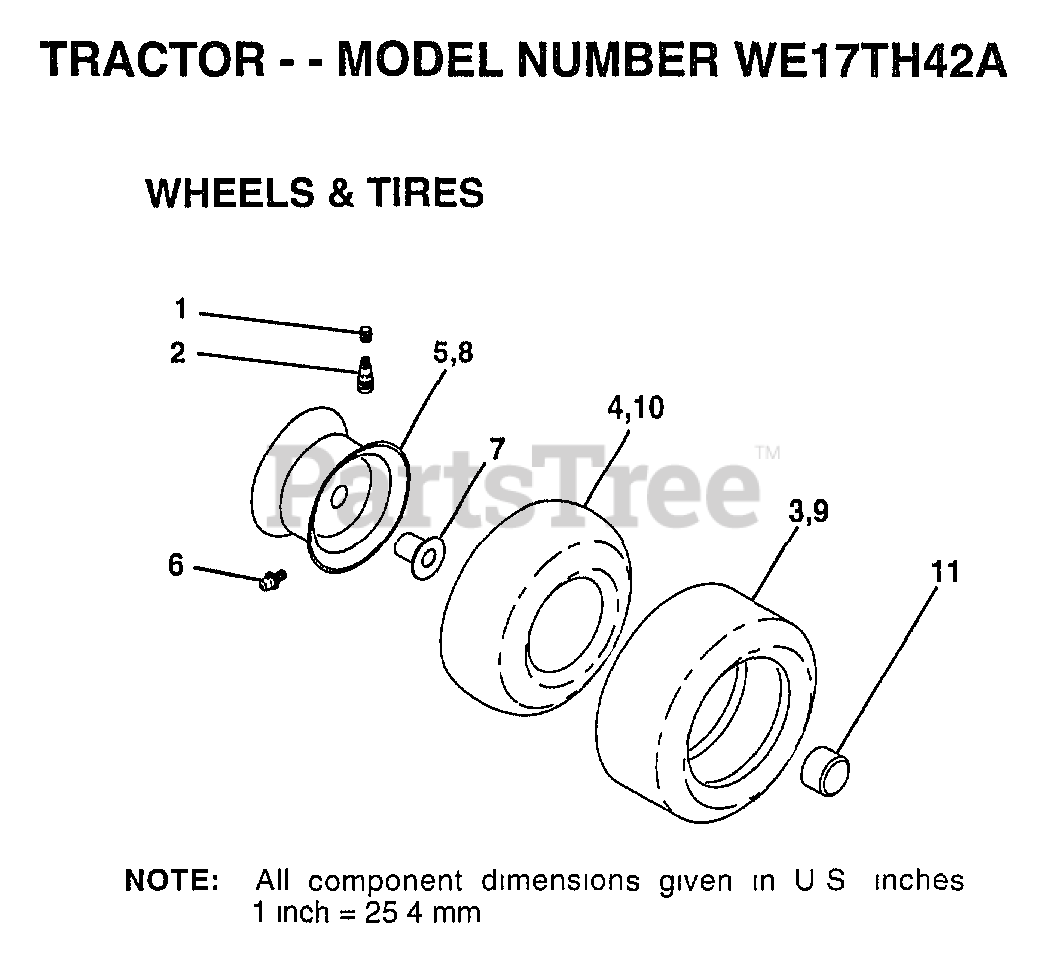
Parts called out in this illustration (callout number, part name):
1	VALVE CAP
2	VALVE STEM LT
4	TUBE.5.3/4.5/6
5	"RIM ASM 6"" FRT"
6	FITTING LT
7	"FLANGE, BEARING"
8	"RIM AS 8"" REAR"
9	TIRE.20X8-8
10	TUBE.18X9.5-8
11	HUB CAP
